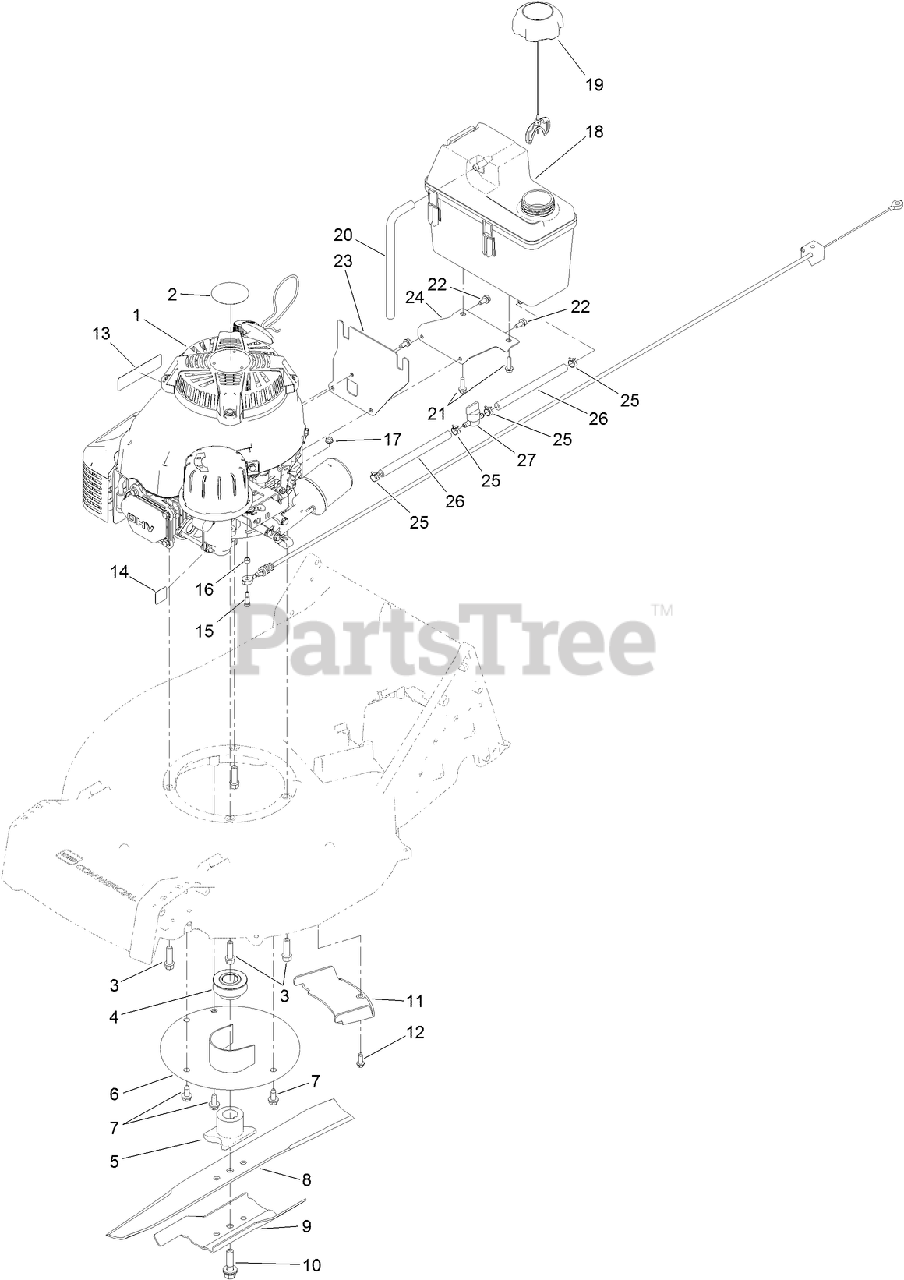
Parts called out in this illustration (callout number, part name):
1	ENGINE-KAWASAKI, FJ180V
3	SCREW-TAPTITE
4	PULLEY-DRIVER
5	DRIVER-BLADE
6	PROTECTOR-CRANKSHAFT
7	SCREW-HWHTF
9	ACCELERATOR-BLADE
10	BOLT-BLADE
11	COVER-BELT
12	SCREW-HWHTF
13	DECAL-ARRESTER, SPARK
14	DECAL-PRIMER
15	SCREW-SHOULDER
16	SPACER
17	NUT-LOCK, FLANGE
18	TANK-FUEL
20	HOSE-VENT, CANISTER
21	SCREW-HWH
22	SCREW-HWH
23	BRACKET-TANK, MOUNTING
24	BRACKET-TANK, SUPPORT
25	CLAMP-HOSE
26	HOSE-FUEL
27	VALVE-FUEL
